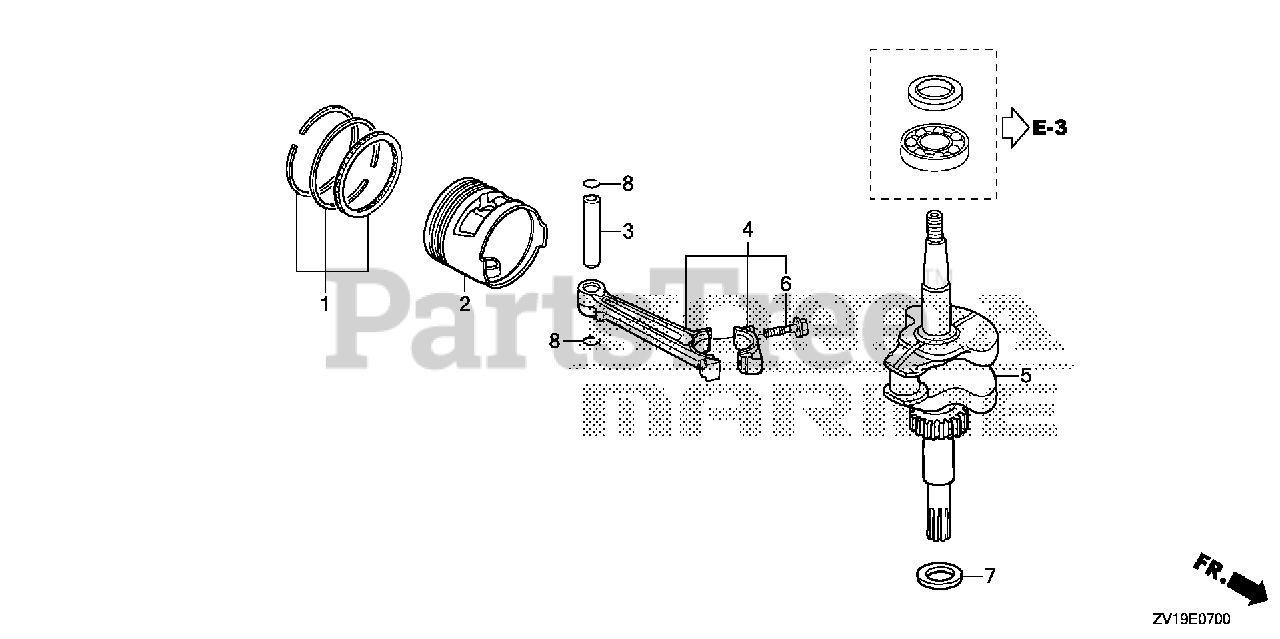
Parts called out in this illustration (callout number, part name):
1	RING SET, PISTON (STD) (TEIKOKU)
3	PIN, PISTON
4	ROD ASSY., CONNECTING
5	CRANKSHAFT
6	BOLT, CONNECTING ROD
6	BOLT, CONNECTING ROD (IDENT MARK Z)
7	WASHER C, THRUST (25MM)
8	CLIP, PISTON PIN (18MM)
